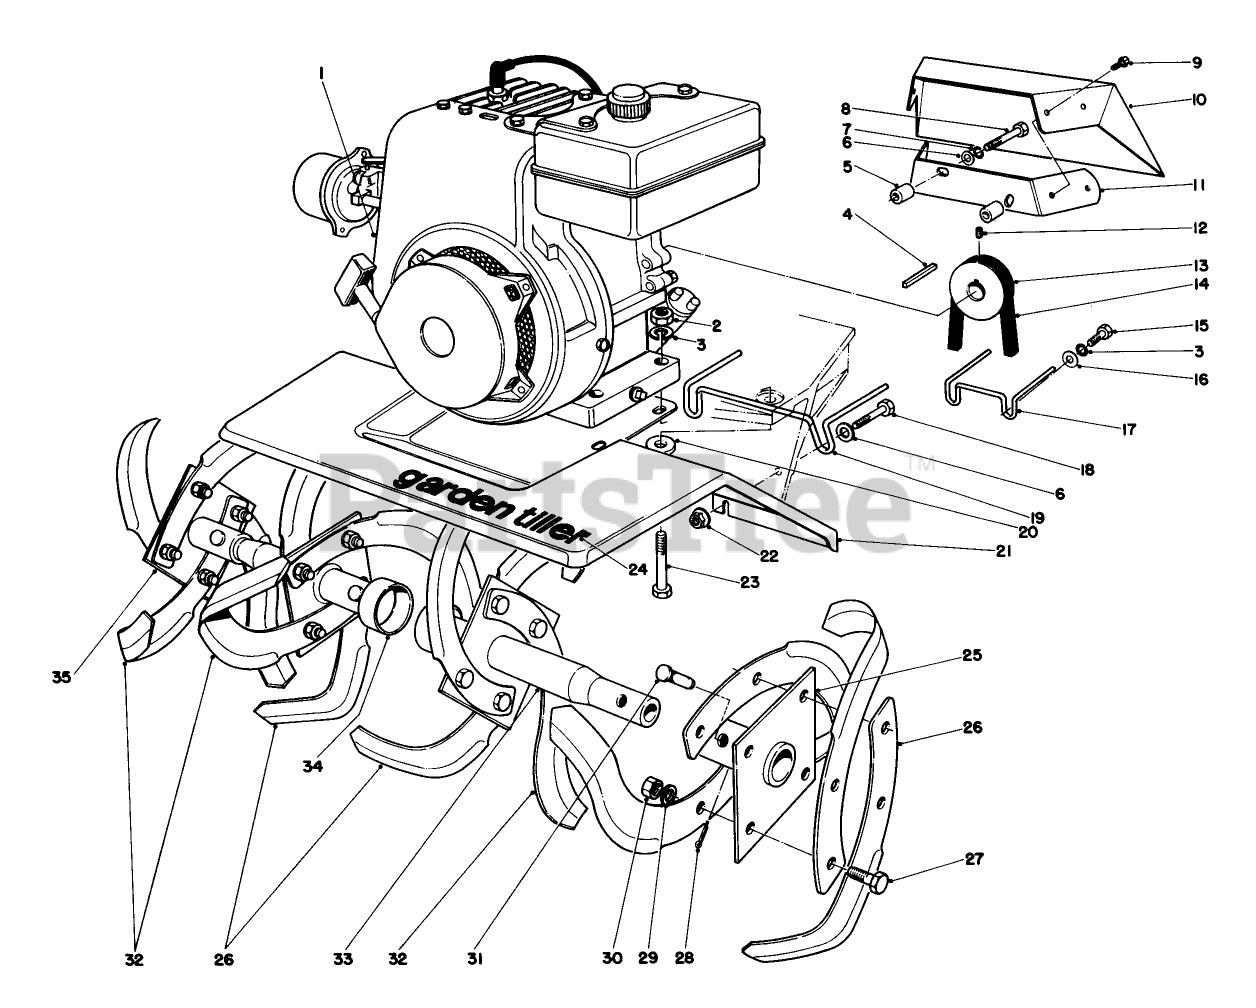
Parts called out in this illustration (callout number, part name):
1	Engine
2	NUT-HEX
3	WASHER-LOCK
4	KEY-SQUARE
6	WASHER-FLAT
7	WASHER-LOCK
8	SCREW-HH
9	SCREW-HWHTF
12	SCREW-SET
14	V-BELT
15	SCREW-HH
16	WASHER-PLAIN
18	SCREW-HH
20	WASHER-FLAT
22	NUT-LOCK, HHF
23	SCREW-HH
26	RH TINE
27	SCREW-HH
28	PIN-COTTER
29	WASHER-LOCK
30	NUT-HEX
31	TINE PIN
